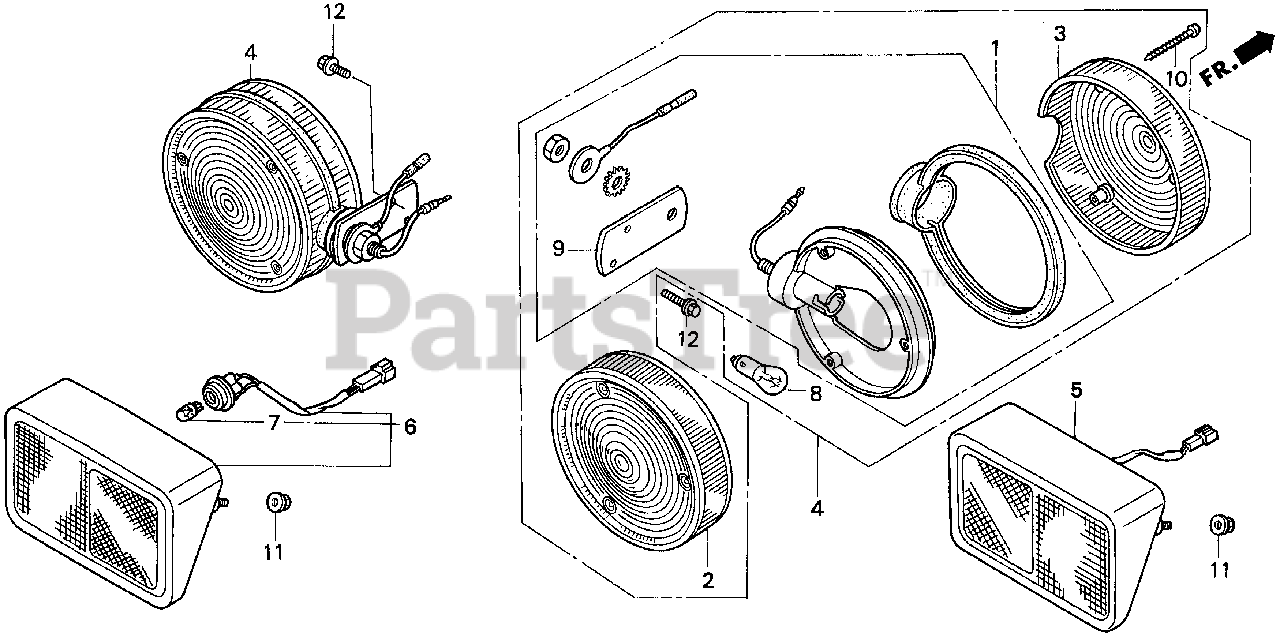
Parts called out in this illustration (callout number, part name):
1	BASE, TURN SIGNAL
2	LENS, TURN SIGNAL (A)
3	LENS, TURN SIGNAL (B)
4	LIGHT ASSY., FLASHING WARNING
5	TAILLIGHT ASSY., R.
6	TAILLIGHT ASSY., L.
7	BULB (12V5W) (STANLEY)
8	BULB (12V27W 1156)
9	BRACKET, HAZARD LIGHT
10	SCREW, TAPPING (4X40)
11	NUT, FLANGE (5MM)
12	BOLT, FLANGE (6X16)
